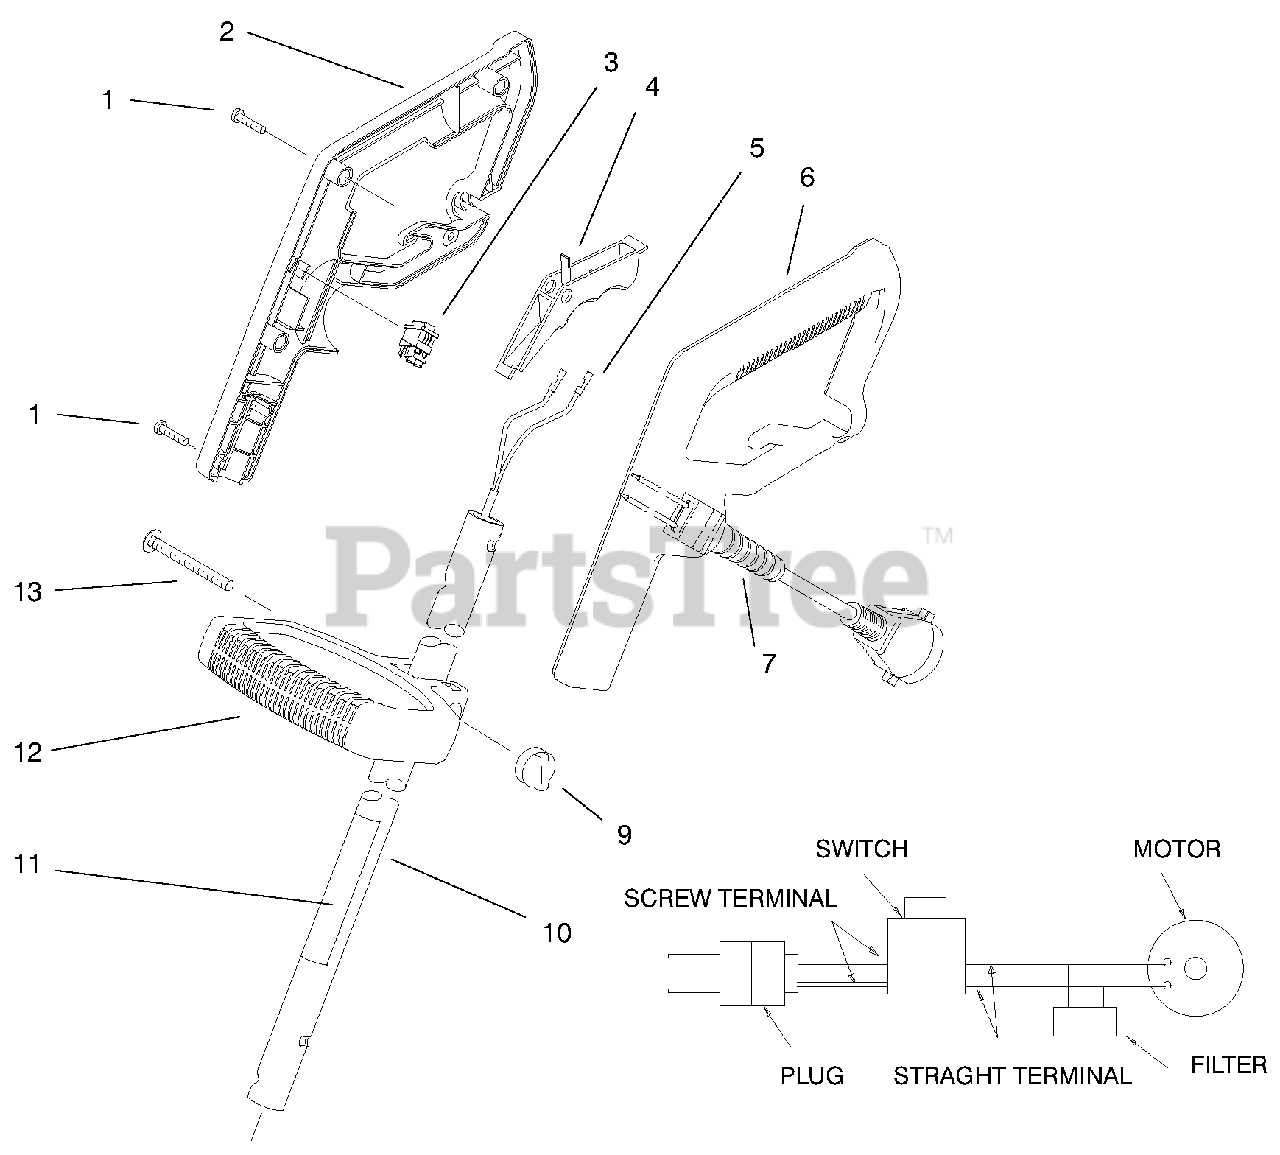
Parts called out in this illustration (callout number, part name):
1	SCREW-PPH
2	Grip-Hand R.H.
3	SWITCH - 230V
5	HARNESS - WIRE
6	Grip-Hand L.H.
7	CORD - POWER
9	KNOB, VFL/FFL
10	Tube Assembly (Incl. Ref. #11)
11	DECAL - WARNING
12	MID HANDLE
13	SCREW-CARR
